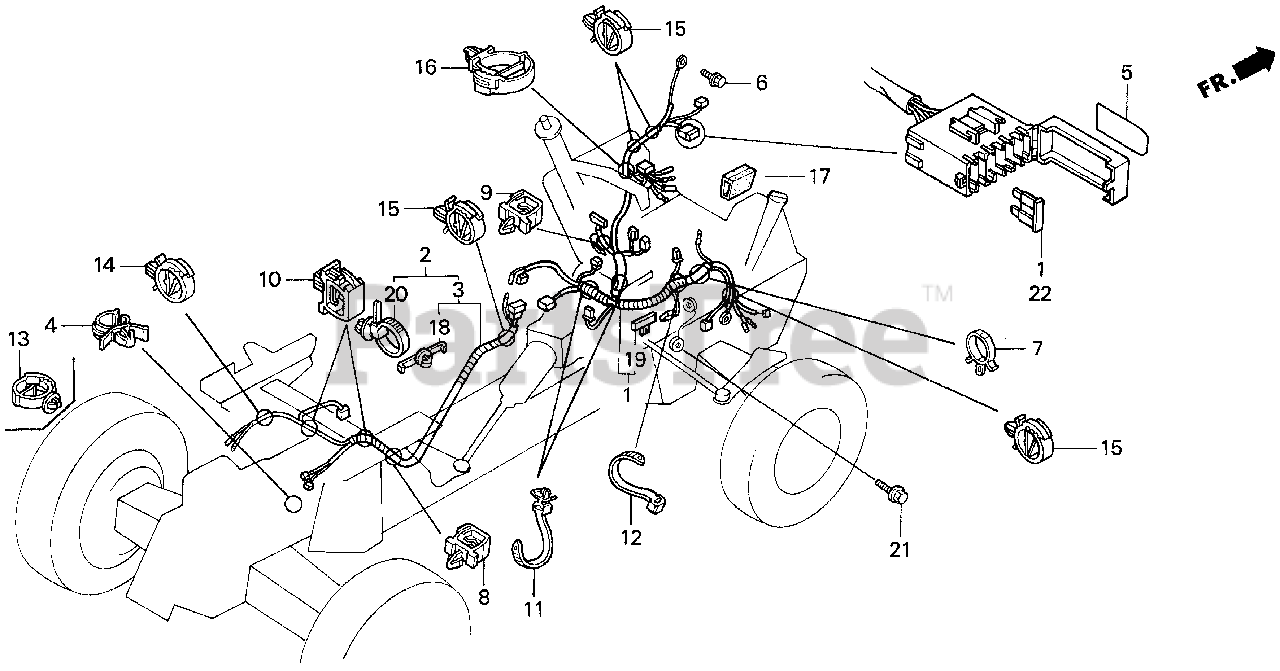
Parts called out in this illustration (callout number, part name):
1	WIRE HARNESS ASSY., MAIN
3	SUB-WIRE HARNESS ASSY., RR.
4	CLIP, WIRE HARNESS
4	CLIP, WIRE HARNESS (25MM)
5	MARK, BRANCH FUSE (ENGLISH)
6	BOLT, FLANGE (6X12) (CT200)
7	CLIP, WIRE HARNESS
8	CLIP, WIRE HARNESS (10MM)
9	CLIP, WIRE HARNESS (13MM) (GRAY)
10	CLIP, HARNESS (10MM)
11	STRAP, CABLE (118MM) (BLACK)
12	BAND, CABLE (120MM) (BLACK)
14	CLIP, WIRE HARNESS (25MM)
15	CLIP, HARNESS
16	STRAP, WIRE HARNESS (25MM) (BLACK)
17	TUBE, FASTENER (30MM)
18	CLIP, WIRE HARNESS (50MM) (GRAY)
19	CLIP, WIRE HARNESS
21	BOLT, FLANGE (8X12)
22	FUSE, BLADE (7.5A)
